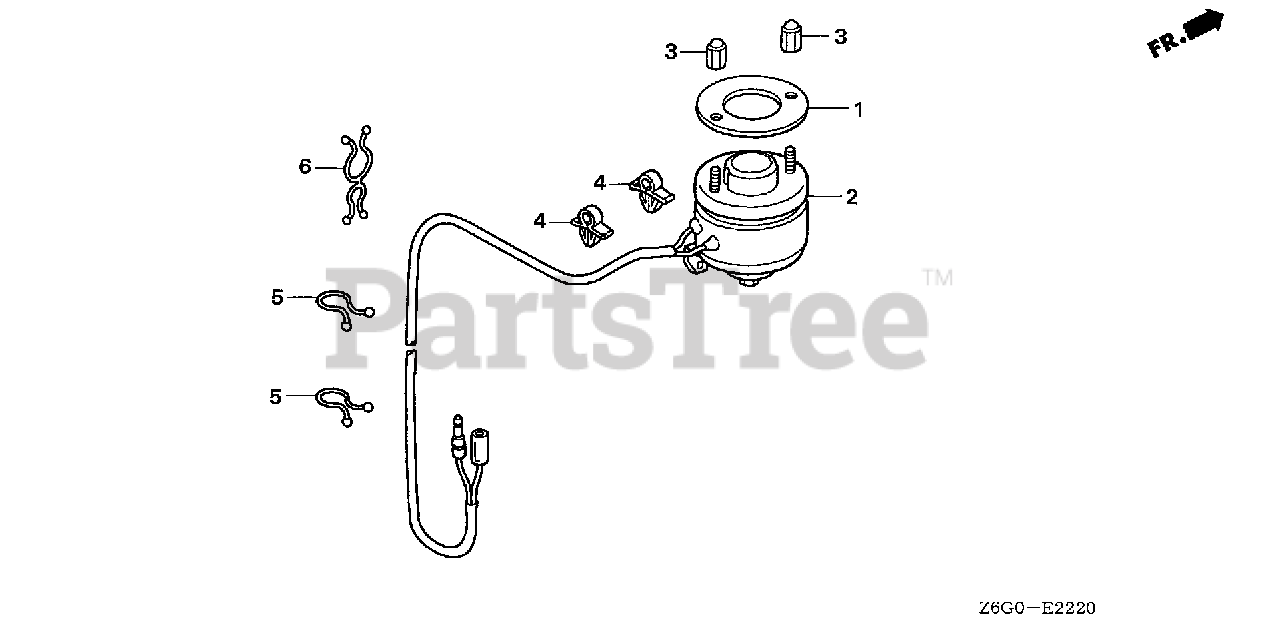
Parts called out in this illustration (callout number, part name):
1	PLATE, SOLENOID
2	SOLENOID ASSY., ROTARY
3	NUT, SPECIAL CAP
4	CLIP, WIRE HARNESS (6MM) (WHITE)
5	PURSE, LOCK (8MM)
6	CLIP, PURSE LOCK
